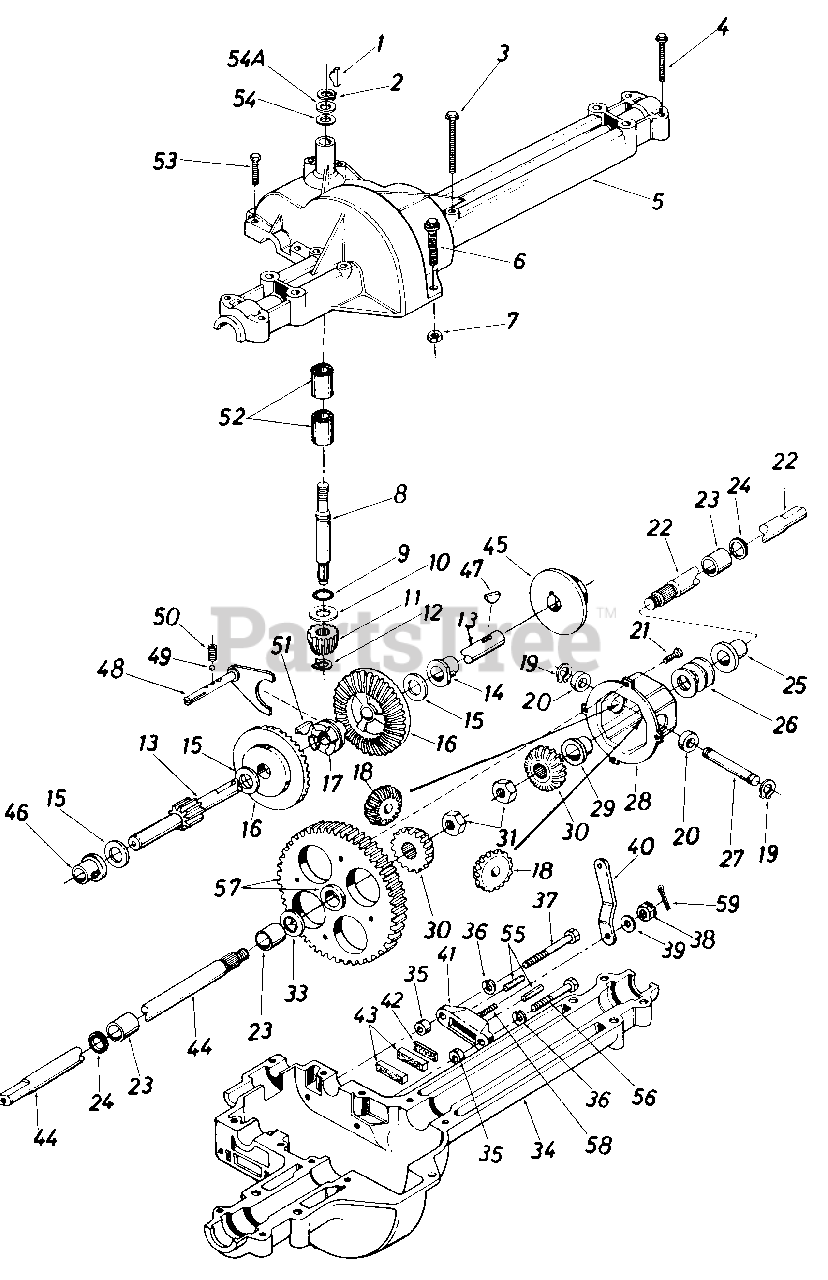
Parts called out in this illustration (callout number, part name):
1	#4 Hi-Pro Key 3/32 x 5/8" Dia.
2	Snap Ring .625" Shaft
3	Hex Bolt 1/4-20 X 1.75" Lg.
4	Hex Bolt 1/4-20 X 1.25" Lg.'r
5	Upper Housing
6	Hex Fl-Bolt 1/4-20 X .88" Lg.
7	Hex Nut 1/4-20 Thd.
8	Input Shaft
9	Square Seal 5/8" I.D.
10	Thrust Washer 5/8" I.D. x 1.25" O.D.
11	Pinion Input 14T
12	Retaining Ring 7/16" Ext.
13	Drive Shaft R.H.
14	Flange Brg. 5/8" I.D. x 3/4" Lg.
15	Fl-Wash.
16	Bevel Gear 42T
17	Clutch Collar
18	Miter Gear 15T H.D.
19	Snap Ring
20	Thrust Bearing 1/2" I.D. x 1.0" O.D.
21	Pan Head Scr. 1/4-20 X .50" Lg. w/ Patch
23	Sleeve Bearing 3/4" I.D. x 1.0" Lg.
24	Oil Seal 3/4" I.D.
25	Flange Bearing 3/4" I.D. x 15/16" Lg.
26	Fl-Wash. .760" I.D. x 1.49" O.D.
27	Cross Shaft
28	Differential Housing Ass'y.
30	Miter Gear H.D.
31	Hex Ins. L-Nut 1/2-20 Thd.
33	Fl-Wash. .760" I.D. x 1.49" O.D.
34	Lower Housing
35	Spacer .53" O.D. x 3/8" Lg.
36	L-Wash. 1/4" I.D.
37	Hex Bolt 1/4-20 x 1.50" Lg. (Grade 5)
38	Castle Nut 5/16-24 Thd.
39	Fl-Wash. .344" I.D. x .875" O.D .
40	Actuating Arm R.H.
42	Puck Plate
43	Brake Puck
46	Flange Bearing 5/8" I.D. x 15/16" Lg.
47	Woodruff Key 3/16 x 5/8 HT
48	Shift Fork Ass'y.
49	Ball Detent .250" Dia.
50	Spring Detent
51	#9 Hi-Pro Key 3/16" x 3/4" Dia. HT
52	Needle Brg. 5/8" I.D. x 1/2" Dia. HT
53	Hex Bolt 1/4-20 x 1.00" Lg.
54	Fl-Wash. 5/8" I.D. x .030
54A	Fl-Wash. 5/8" I.D. x .040
55	Actuating Pin 5/16" Dia.
56	Hex Bolt 1/4-20 x 1.50" Lg. (Grade 5)
57	Differential Gear 72T Ass'y. w/ Bearing
58	Sq. Hd. Bolt 5/16-24 Thd.
59	Cotter Pin 3132" Dia. x .50" Lg.
